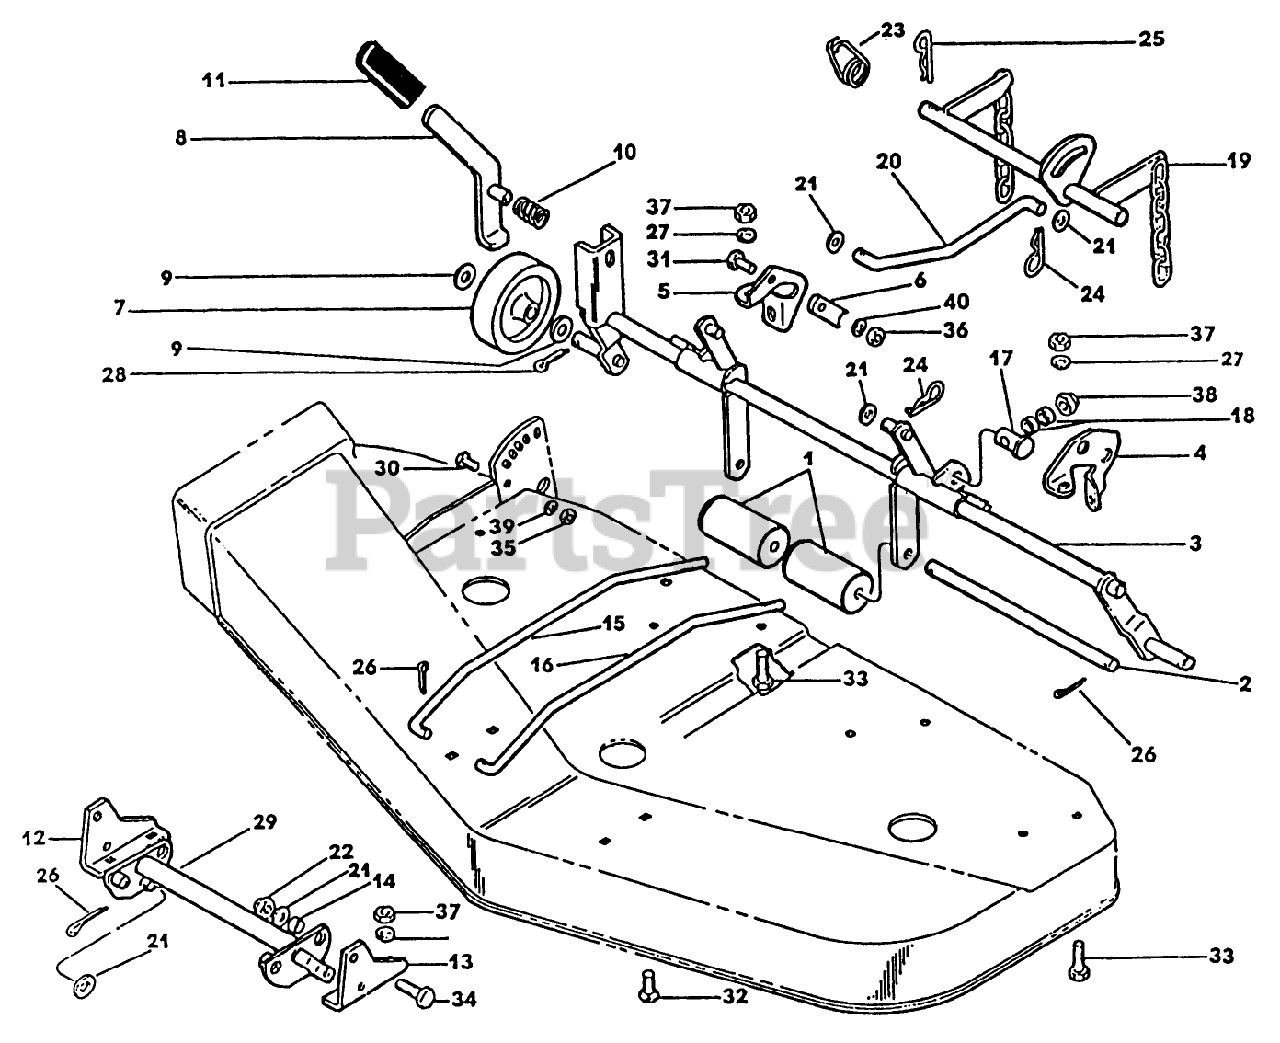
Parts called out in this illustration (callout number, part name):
2	SHAFT - ROLLER
7	WHEEL - MOWER
17	PIN - PIVOT
19	BELLCRANK ASSEMBLY *B
20	LINK - MOWER LIFT
22	NUT-LOCKING
24	PIN-HAIR
30	SCREW-HH
31	SCREW - HEX
38	NUT-HEX CONE LOK
